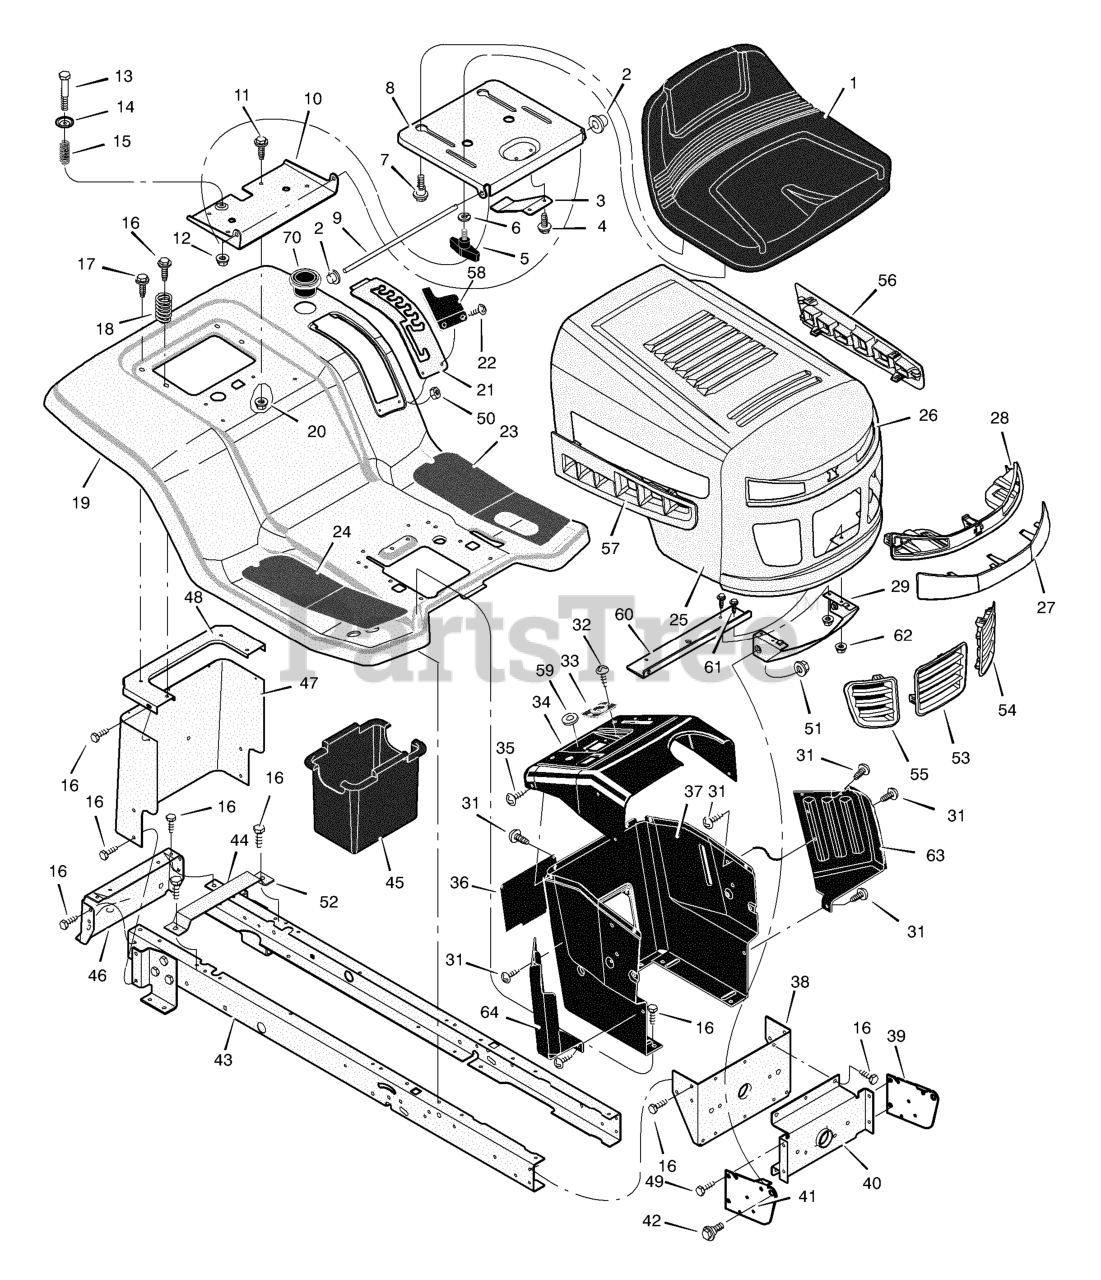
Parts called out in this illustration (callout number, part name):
1	Seat
2	Cap, Push On
5	Bolt, Wing
6	Washer
7	Bolt, Shoulder
8	Support, Seat
9	Rod, Pivot
10	Bracket, Pivot
11	Bolt
13	Bolt, Shoulder
15	Spring
19	Deck, Seat
20	Nut
21	Plate, Index
23	Mat, Left
24	Mat, Right
25	Hood
26	Grille
28	Housing, Light
29	Bracket, Lower Pivot
31	Screw
33	Bearing, Steering
36	Panel, Access
37	Support, Dash
38	Bracket, Rear Hanger
39	Support, Left Grille
40	Axle, Hanger
41	Support, Right Grille
42	Bolt, Shoulder
43	Frame, Right
44	Frame, Left
45	Container, Battery
46	Plate, Hitch
47	Plate, Rear
48	Top, Rear Plate
52	Support, Battery
53	Insert, Center Grille
54	Insert, Left Grille
55	Insert, Right Grille
56	Insert, Left Hood
57	Insert, Right Hood
58	Cover, Detent
59	Grommet, Parking Brake
60	Bracket, Support
62	Nut
63	Panel, Left Side
64	Panel, Right Side
70	Holder, Cup
